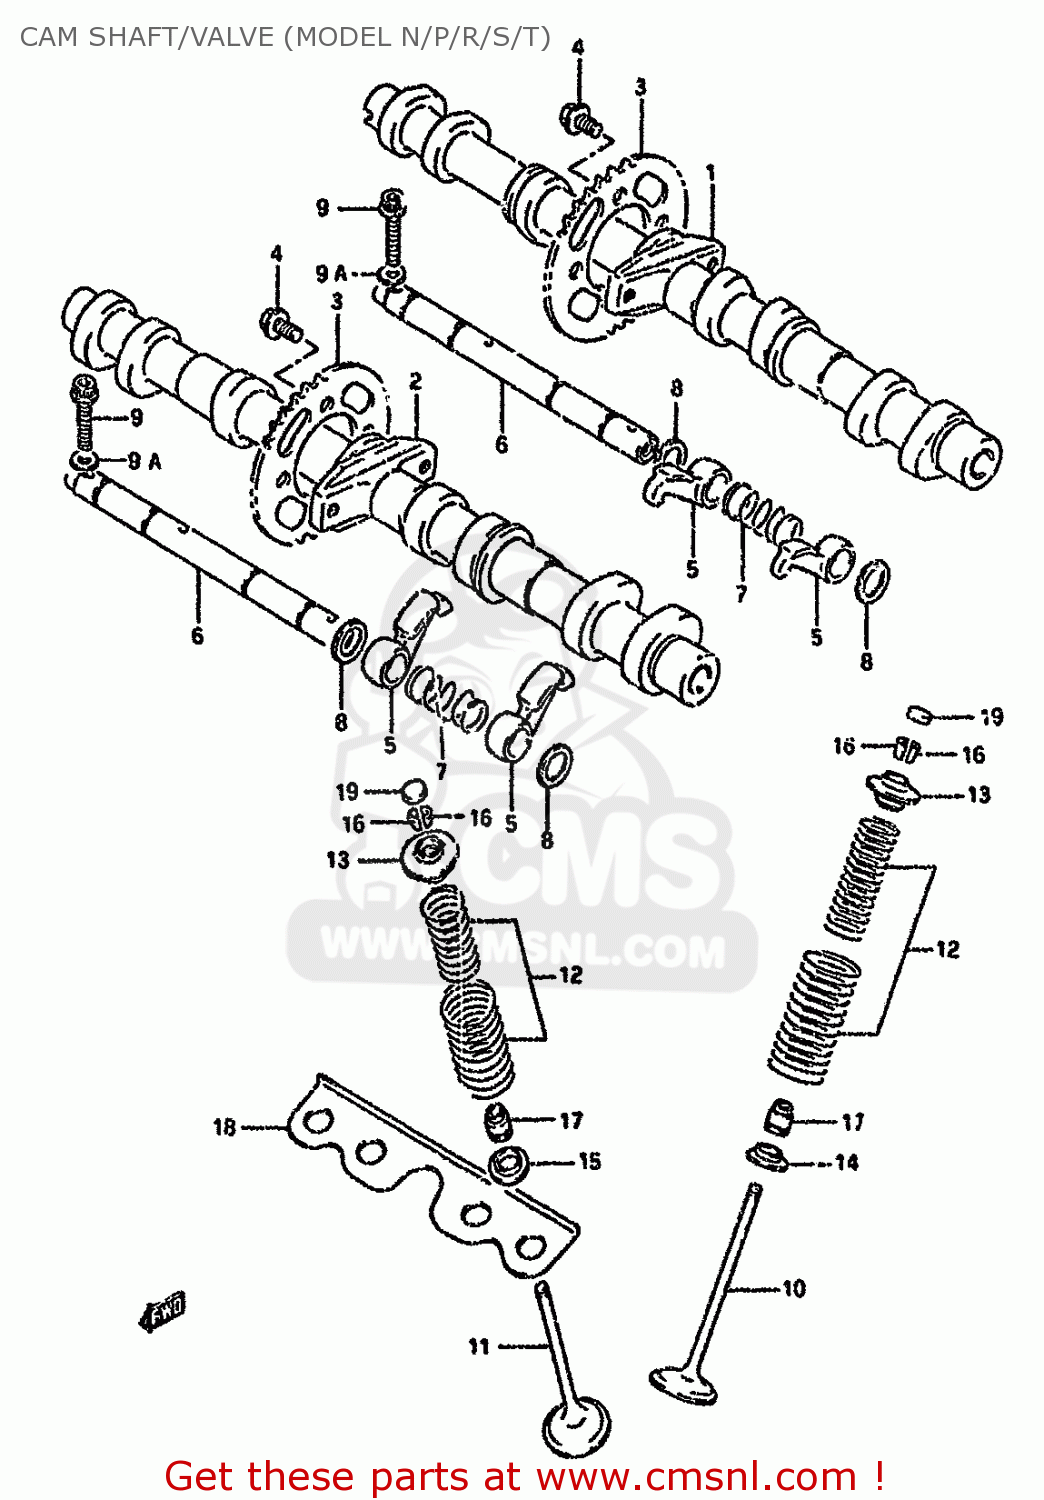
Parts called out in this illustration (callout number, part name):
1	CAMSHAFT INTAK
2	CAMSHAFT,EXHAUST
3	SPROCKET,CAMSHAFT
4	BOLT(7X11)
5	ARM,VALVE ROCKER
6	SHAFT,VALVE ROCKER ARM
7	SPRING
8	WASHER
9	BOLT
9A	WASHER
10	VALVE,INTAKE
11	VALVE,EXHAUST
12	SPRING SET,VALVE
13	RETAINER,VALVE SPRING
14	SEAT,VALVE SPRING
15	SEAT,VALVE SPRING
16	COTTER VALVE
17	SEAL,OIL(5X10X9.7)
18	PLATE,VALVE SEAT
19	SHIM,TAPPET(T:2.3)
21	CASE,TAPPET SHIM
